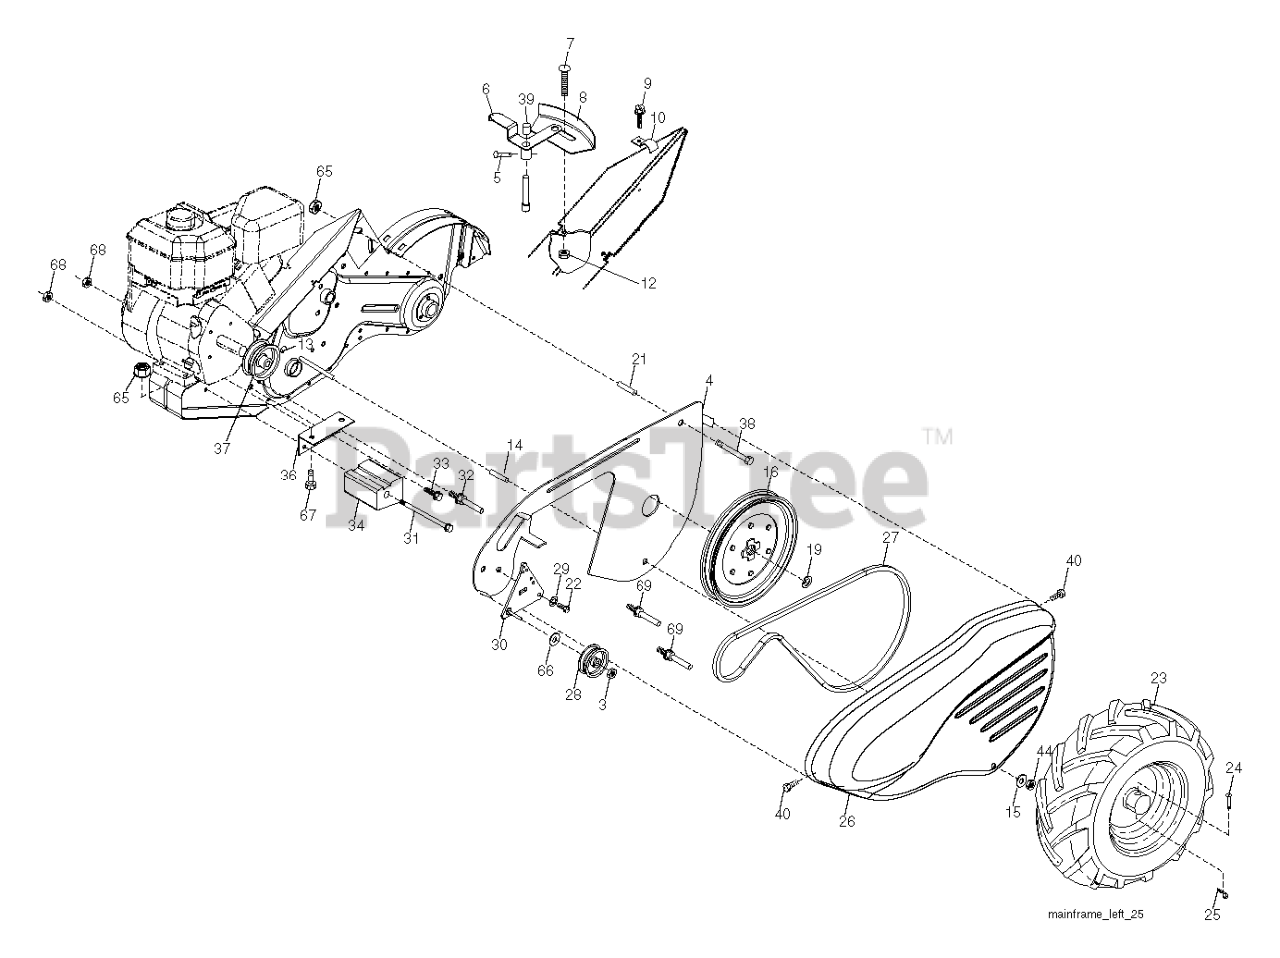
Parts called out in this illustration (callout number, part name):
3	LOCKNUT
4	SHIELD.INNER.BELT.GUARD.RT.BLA
5	PIN.SPIROL.FLARED
6	LEVER.ASM.SHIFT.RED
8	PANEL.INDICATOR.SHIFT.BLACK.
9	TAPPING SCREW
10	CLIP.PLATED
12	NUT
14	SPACER-SPLIT.327 X .42
15	WASHER
16	SHEAVE, TRANSMISSION
19	RETAINING RING LT
21	SPACER SPLIT
23	WHEEL.ASM.DRT.13X5-6.LT.SILVER
24	RIVET
25	RETAINER M
26	GUARD.BELT.TILLER.ORANGE
27	V-BELT
28	PULLEY-IDLER TI
30	BRACKET.IDLER.TILL.STUD.1.50
31	BOLT.FIN.HEX.3/8-16UNC X 11.5
32	SHIFT ARM CRT
33	BOLT
34	COUNTERWEIGHT.LH
36	BRACKET.REINFORCEMENT.LH.PNT
37	RP.ENGINE PULLEY
38	BOLT
39	CAP.PLUNGER.BLACK
40	SCREW.HEX.WSH.SLT.#10-24X.50
44	NUT.71038.31-18.HEX.NYLOCK
65	LOCKNUT-FLANGE 5/16-18
66	WASHER
67	BOLT, HEX 5/16-18X1-3/4
69	KEEPER.BELT.ENGINE
70	WASHER
